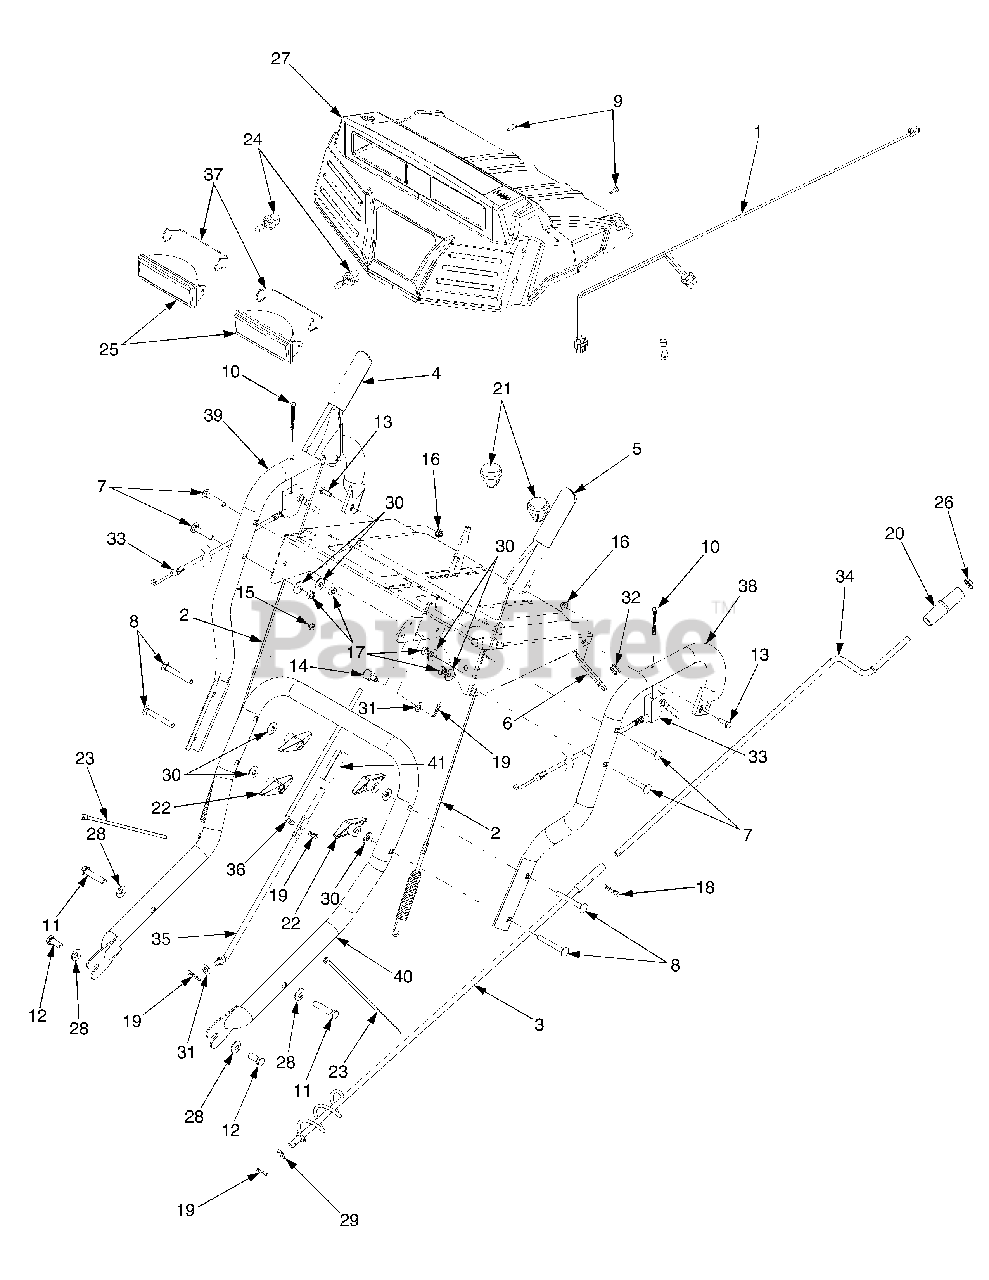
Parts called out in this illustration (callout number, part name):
1	Harness, Headlight Wire
2	Cable Assembly, Auger/Drive Engagement
5	Handle, Egagement, LH
7	Screw, Carriage, 5/16-18 x 1.75
8	Screw, Carriage, 5/16-18 x 2.5
9	Screw, Hex Wash Hd Tapp, #10-16 x .625
10	Screw, Oval Hd C/Sunk, #10-24 x 1.75
11	Screw, Hex Patch Lock, 3/8-16 x 1,75 GR5
12	Screw, Hex Patch Lock, 3/8-16 x .88 GR5
13	Screw, Hex Cap, 1/4-20 x .75 GR5
14	Ferrule, 5/16-18 x .312 Dia
15	Nut, Hex Sems, 1/4-20
16	Nut, Hex Flange Insert Lock, 1/4-20 GrF
17	Nut, Hex, 5/16-18 GR5
18	Pin, Internal Cotter
19	Pin, Internal Cotter
20	Knob, Crank
21	Knob, Shift
22	Knob, Wing Nut, 5/16-18
23	Tie, Cable
24	Lamp, Halogen, 27W
25	Housing, Lamp
26	Cap, Push, 3/8
27	Panel, Handle
27	Graphic, Left Turn/Auger Control
27	Graphic, Chute Tilt/Shift
27	Graphic, Starting Instr/Drive Control
27	Graphic, Drive/Auger Lock
27	Graphic, Cub Cadet
27	Graphic, 928 SWE 28" S.T. Only
27	Graphic, 933 SWE 33" S.T. Only
27	Graphic, 945 SWE 45" S.T. Only
28	Washer, Belleville, .375 x .87 x .063
29	Washer, Flat, .375 x .738 x .063
30	Washer, Belleville, .34 x .872 x .06
31	Washer, Flat, .344 x .688 x .065
32	Bushing, Plastic, .38 ID
33	Cable Assembly, Trigger Control
35	Rod, Lower Shift
36	Rod, Upper Shift
37	Retainer, Headlight
41	Connector, Shift Rod
